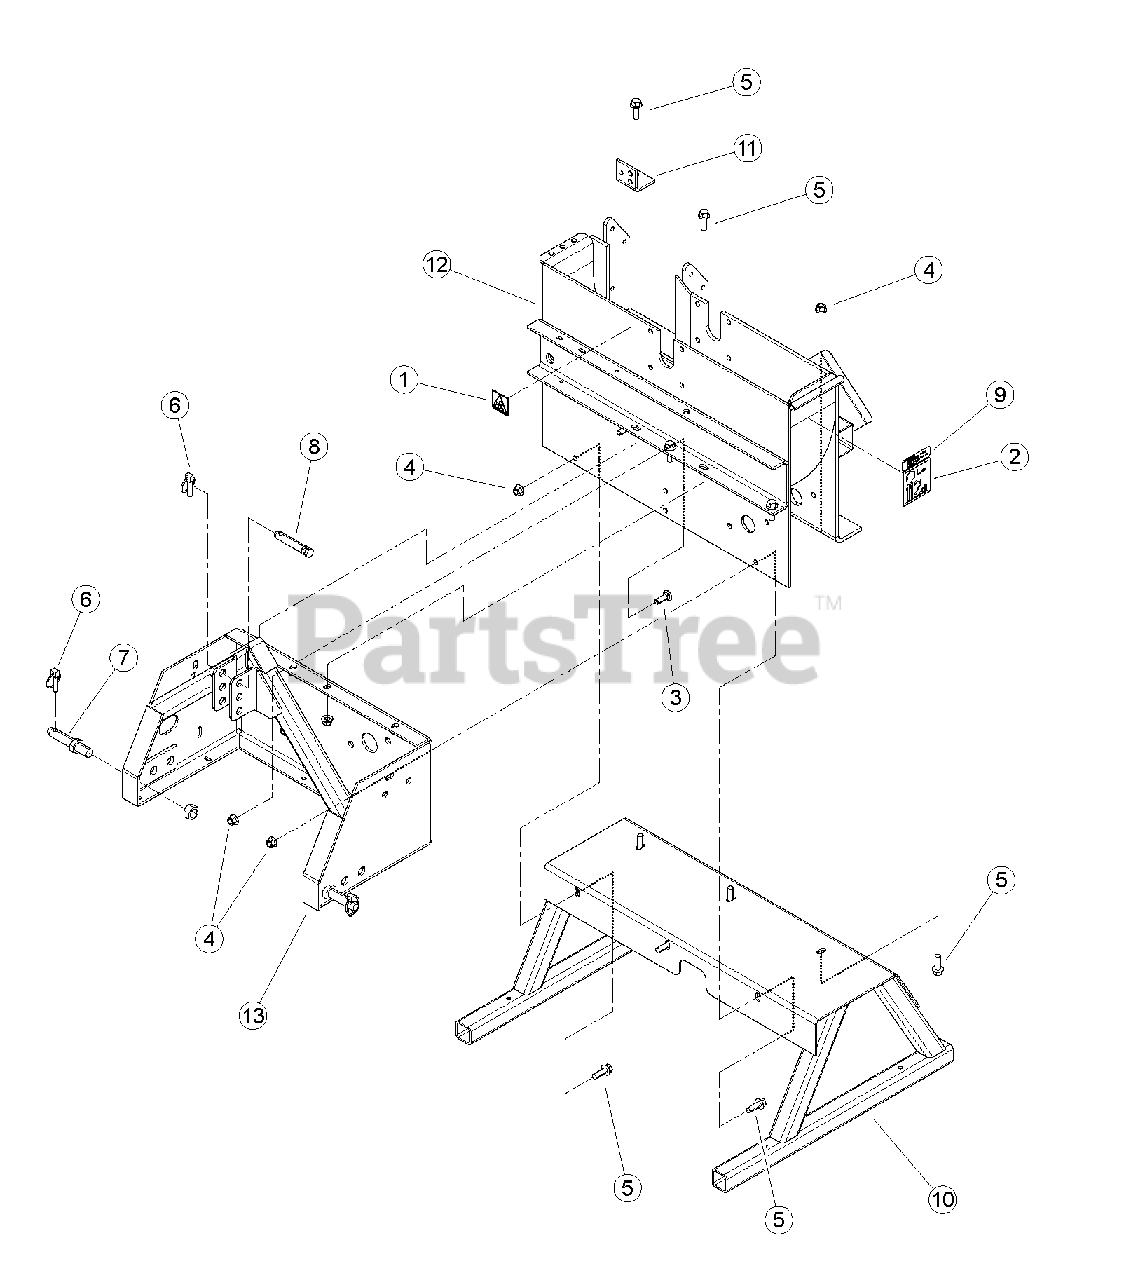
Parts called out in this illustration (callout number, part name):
1	DECAL, SHIELD DANGER ISO
2	DECAL, 112 DB (CE COMPLIANT ONLY)
3	BOLT, 1/2 X 1-1/2" GR5 ZP CRG
4	NUT, 1/2-13 NYLOCK FLANGE
5	BOLT, 1/2-13 X 1-1/2 GR5 FLANGE NC
6	PIN, 7/16 X 1-3/4 LYNCH
7	PIN, LIFT ARM 7/8 X 5" LG
8	PIN, TOP LINK 3/4 X 4-1/2" LG
9	DECAL, ATLANTIC BRIDGE LTD INFO (CE COMPLIANT ONLY)
10	WELDMENT, PTO STAND
11	ANGLE, LOWER SHOCK
12	WELDMENT, CHIPPER BOTTOM
13	WELDMENT, HITCH SUPPORT
